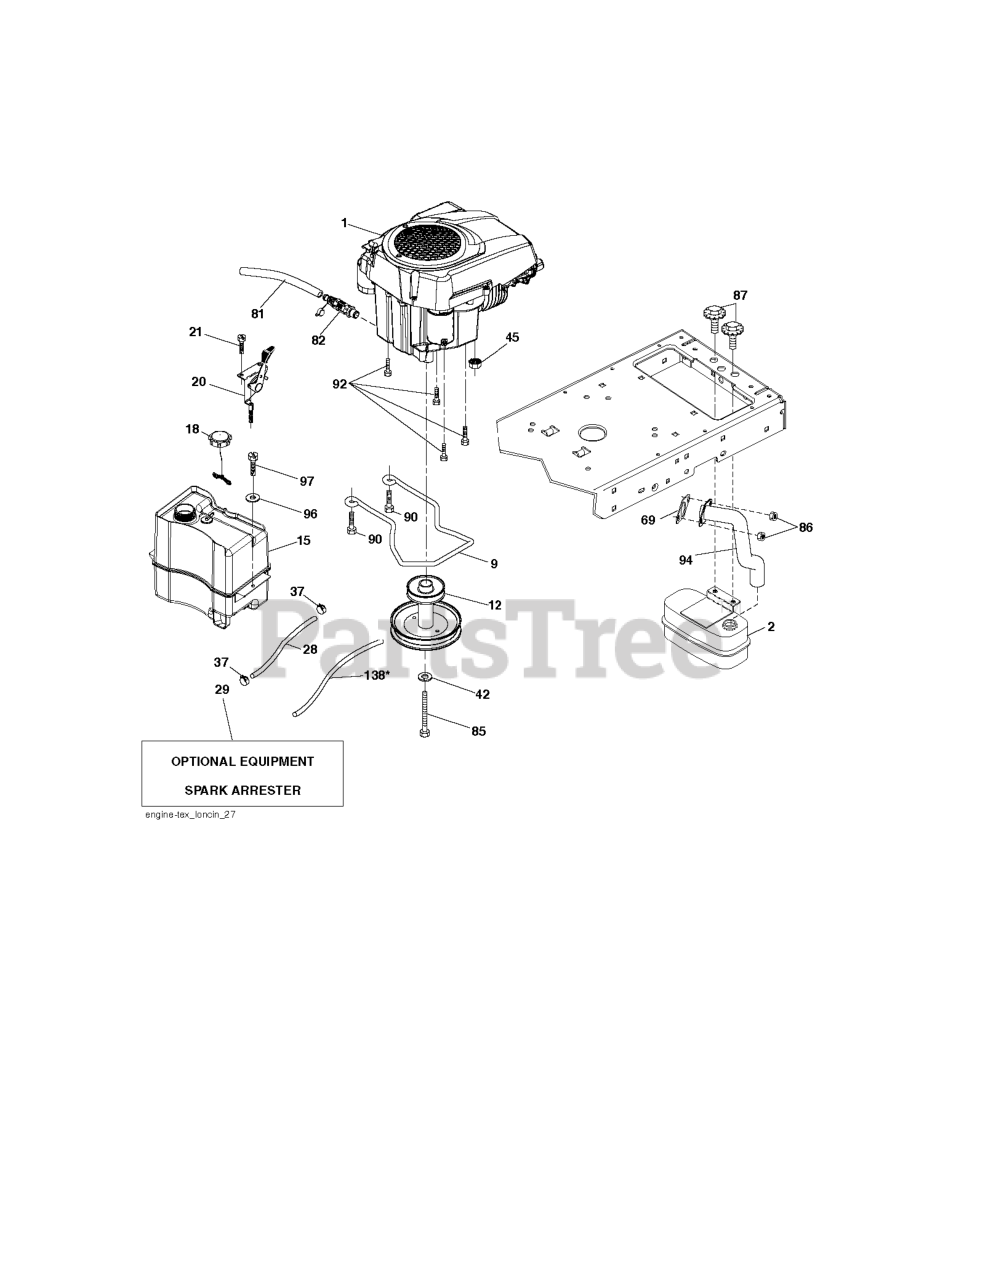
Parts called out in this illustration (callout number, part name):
1	ENGINES
2	MUFFLER.ASM.SINGLE
12	ENGINE.PULLEY
18	CAP.FUEL.2 WAY VENT
20	CONTROL.TH/CK.C.
28	LINE.FUEL.64"REAR.EMIS
29	KIT.SPARK ARRESTOR 794945 B&S
37	HOSE CLAMP
45	NUT HEXAGON WITH FLANGE, SERRA
69	GASKET GASKET.EXHAUST. LONCIN
81	TUBE, DRAIN OIL ASM.
82	VALUE.OIL.DRAIN
85	BOLT.HEX.7/16-20X4.GR5.1.5BLUE
86	NUT.HEX.FLANGE.TOPLOCK
87	BOLT.5/16-18UNCX3/4 W/SEMS.BLK
90	SCREW 3/8-16X1
92	SCREW 3/8-16X1
94	TUBE TUBE.EXHAUST.LONCIN 608.T
97	SCREW HEXWSHR 1/4-20X3/4
138	TUBE.PURGE.FUEL.1875
